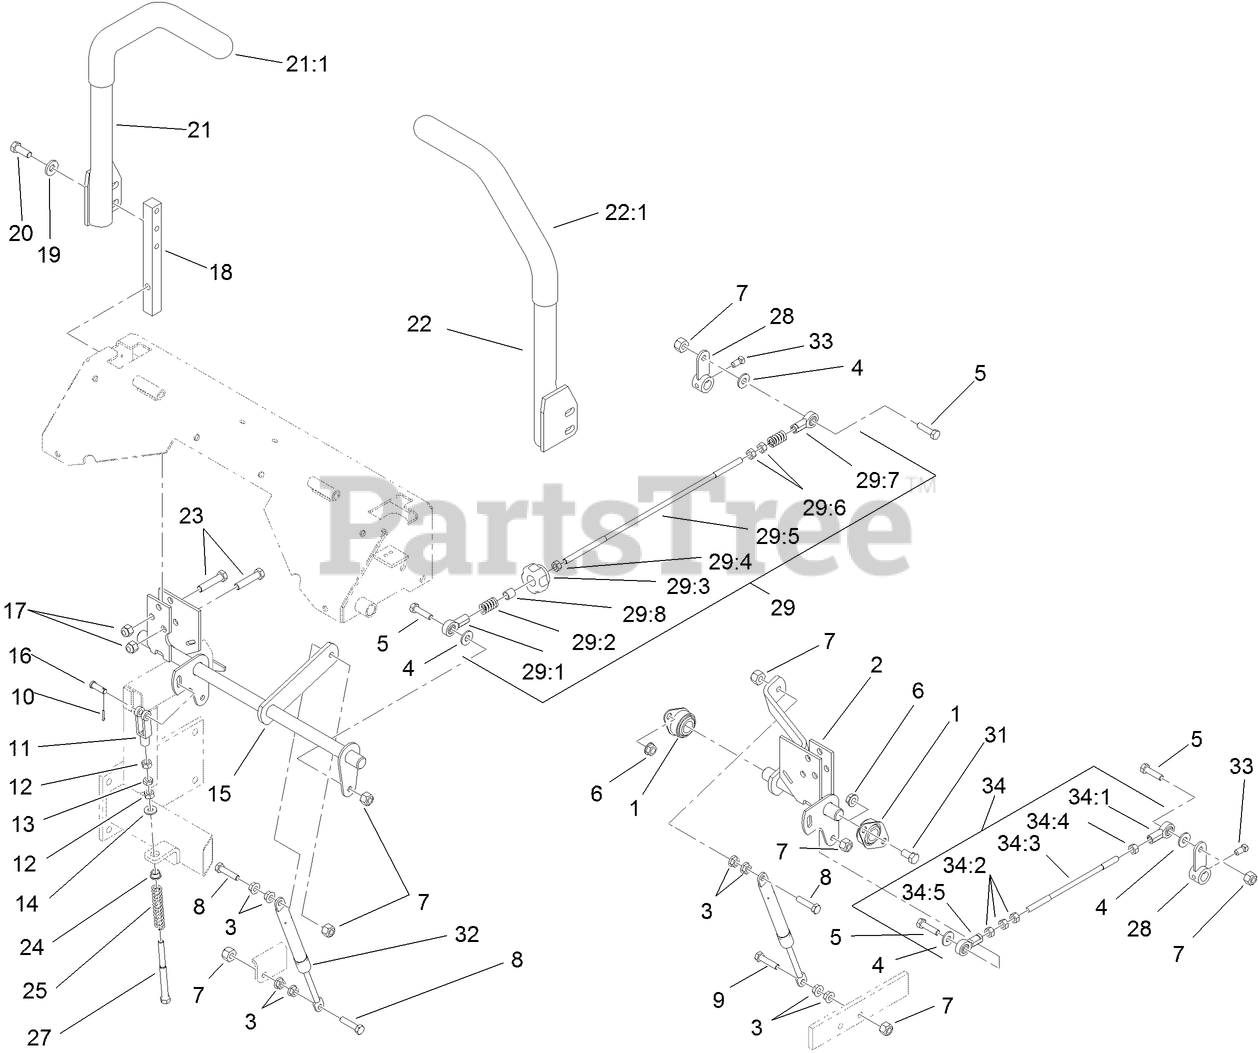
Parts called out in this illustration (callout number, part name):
1	BEARING-FLANGE, SIDE
2	CONTROL-MOTION, LH
3	NUT-HF
4	WASHER-FLAT
5	SCREW-HH
6	NUT-HHF, WHIZ
7	NUT-LOCK, NI
8	SCREW-HH
9	SCREW-HH
10	SCREW-HH
11	YOKE-ADJUSTABLE
12	NUT-HEX
13	NUT-JAM
14	WASHER-FLAT
15	CONTROL-MOTION, RH
16	PIN-CLEVIS
17	NUT-LOCK, NI
18	ARM-SHAFT, CONTROL
19	WASHER-BELLEVILLE
20	SCREW-HH
21	RH LEVER ASM
21:1	GRIP-CONTROL, MOTION
22	LH LEVER ASM
22:1	GRIP-CONTROL, MOTION
23	SCREW-HH
24	BUSHING-FLANGED
25	SPRING-RETURN, NEUTRAL
27	BOLT-RETURN, NEUTRAL
28	ARM-CONTROL, HYDRAULIC
29	RH CONTROL ROD ASM
29:1	BALLJOINT-RH
29:2	SPRING-COMPRESSION
29:3	KNOB-TRACKING
29:4	NUT-HEX
29:7	BALLJOINT-LH
29:8	SPACER-TUBE, PUMP LINK
31	SCREW-HH
32	DAMPER-CONTROL, MOTION
33	SCREW-SET
34	LH CONTROL ROD ASM
34:1	BALLJOINT-RH
34:2	NUT-HEX
34:5	BALLJOINT-LH
